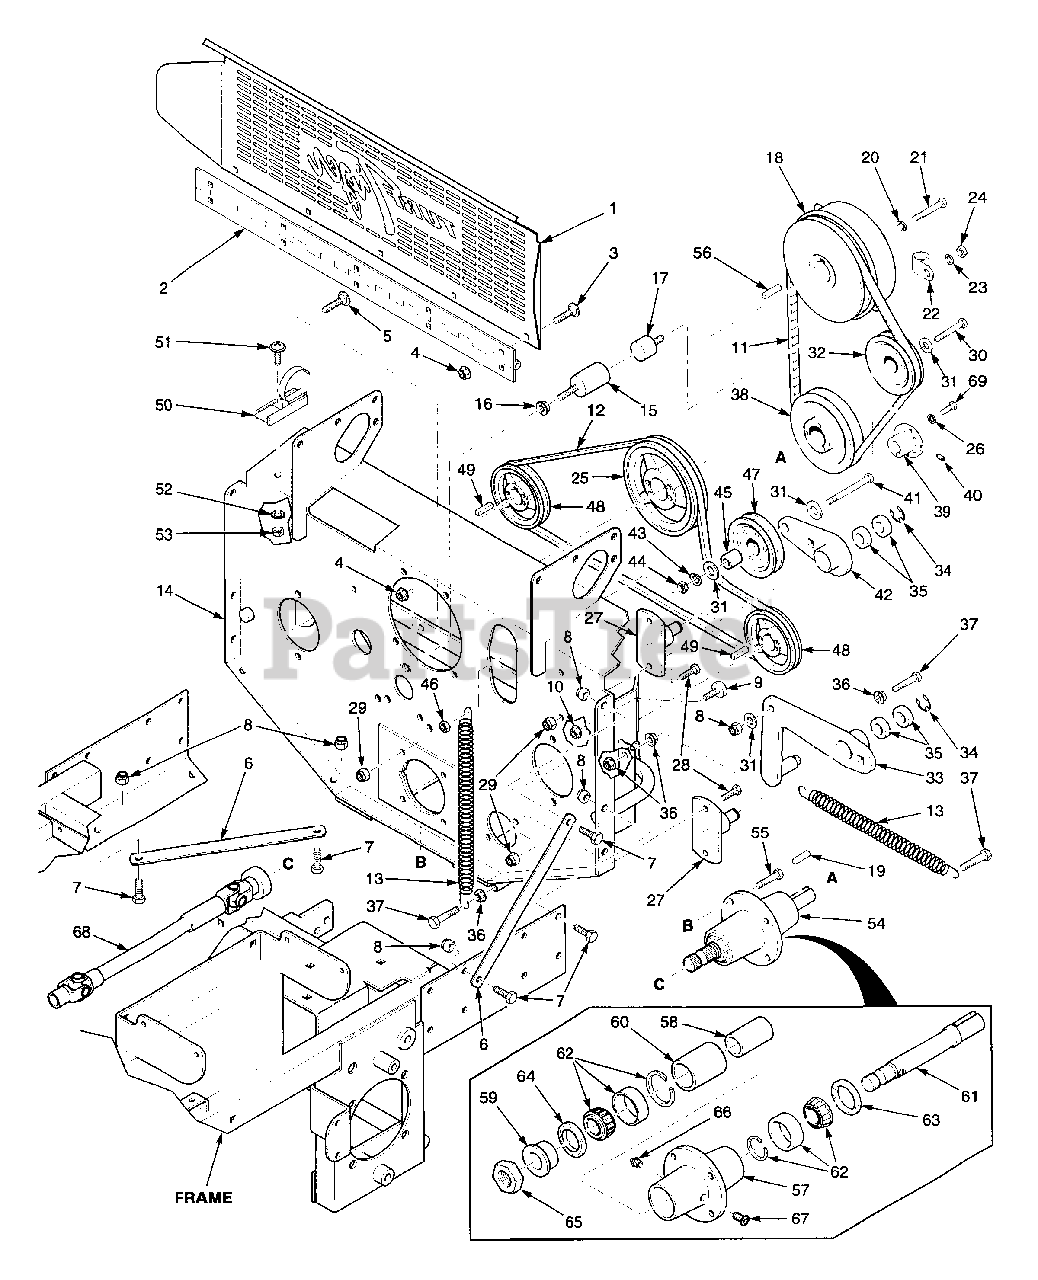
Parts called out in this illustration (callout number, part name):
1	Belt Guard
2	Hinge, Belt Guard
3	Bolt, Carriage 1/4-20 x 1/2"
4	Nut, Hex Serrated Flange 1/4-20
5	Bolt, Carriage 1/4-20 x 3/4"
6	Brace, Engine Mounting
7	Bolt, Hex Head 3/8-16 x 1"
8	Nut, Hex Elastic Stop 3/8-16
9	Bumper, Rubber
10	Nut, Hex Serrated Flange 5/16-18
11	Belt, Deck Drive
12	Belt, Pump Drive
13	Spring, Main Drive
14	Pump Mounting Weldment
15	Base, Clutch Anti-Rotation
16	Nut, Hex Serrated Flange 7/16-14
17	Isolator, Rubber
18	Electric Clutch
19	Key, 1/4 x 1/4 x 1-1/2"
20	Lockwasher, 7/16"
21	Bolt, Hex Head 7/16-20 x 2-1/2"
22	Clamp, Cable 1/2" ID.
23	Lockwasher, 5/16"
24	Nut, Hex 5/16-18
25	Pulley, 6.00 OD. 1.125 Bore
26	Lockwasher, 1/4"
27	Pivot Weldment, Idler
28	Bolt, Hex Head 5/16-18 x 1"
29	Nut, Hex Elastic Stop 5/16-18
30	Bolt, Hex Head 3/8-16 x 2-1/4"
31	Flatwasher, 3/8" (.391 x .938 x .105)
32	Pulley, Idler
33	Idler Arm W/Bearings
34	Ring, Retaining
35	Ball Bearings
36	Nut, Hex Serrated Flange 3/8-16
37	Bolt, Hex Head 3/8-16 x 1-1/2"
38	Pulley, 6.35 Dia. Taper Bore
39	Tapered Hub, 1.00 Bore
40	Setscrew, Hex Socket 1/4-20 x 1/2"
41	Bolt, Hex Head 3/8-16 x 3-3/4"
42	Idler Arm Assembly
43	Lockwasher, 3/8"
44	Nut, Hex 3/8-16
45	Spacer
46	Locknut, Hex Center Lock 3/8-16
47	Pulley, Idler 5.00 Dia.
48	Pulley
49	Key, 5 x 5 x 25 mm
50	Latch, Hood
51	Screw, Phillips Washer Head #10-32 x 1/2"
52	Lockwasher, #10-32 External Tooth
53	Nut, Hex #10-32
54	Spindle Assembly
55	Bolt, Hex Head 5/16-18 x 1-1/4"
56	Key, 1/4 x 1/4 x 1"
57	Spindle Housing
58	Spacer, Inside
59	Spindle Bushing, Bottom
60	Spacer, Outside
61	Shaft, PTO Deck Drive
62	Roller Bearing Assembly
63	Seal, 2.00 OD. x 1.50 Bore
64	Seal, 2.00 OD. x 1.625 Bore
65	Nut, 1.06-18
66	Grease Fitting 1/4-28 Self Tap
67	Relief Fitting
68	Drive Shaft
69	Bolt, Hex Head 1/4-20 x 1-3/8" Full Thread
